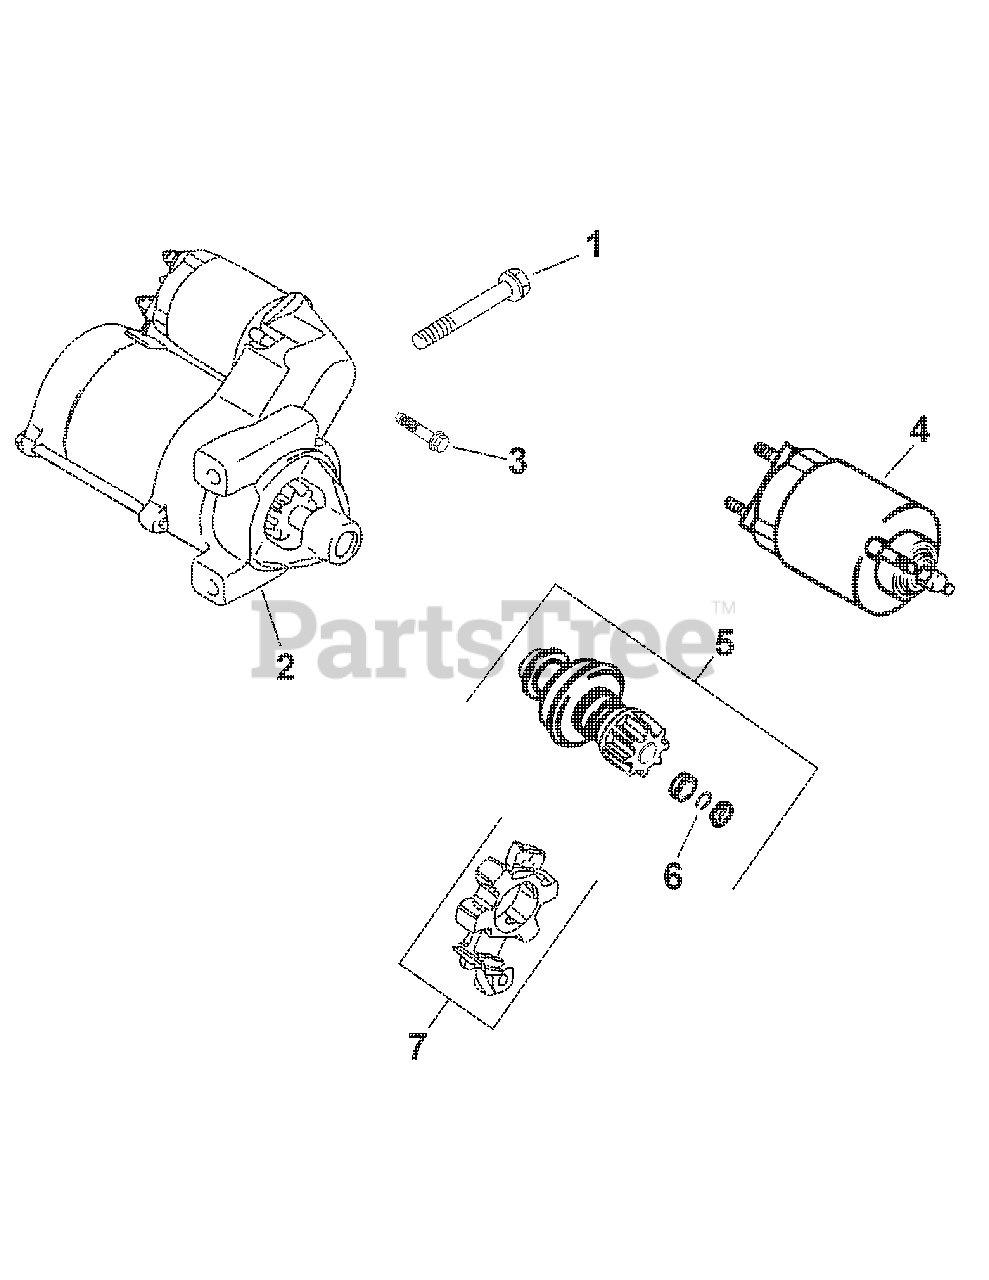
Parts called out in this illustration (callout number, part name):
1	Screw, hex. Flange M8x1.25x80 (2)
2	Starter, solenoid assembly (Includes 3-7)
3	Screw, external torx hd
4	Kit, solenoid (Includes
5	Kit, starter pinion (Includes 6)
7	Brush, holder
